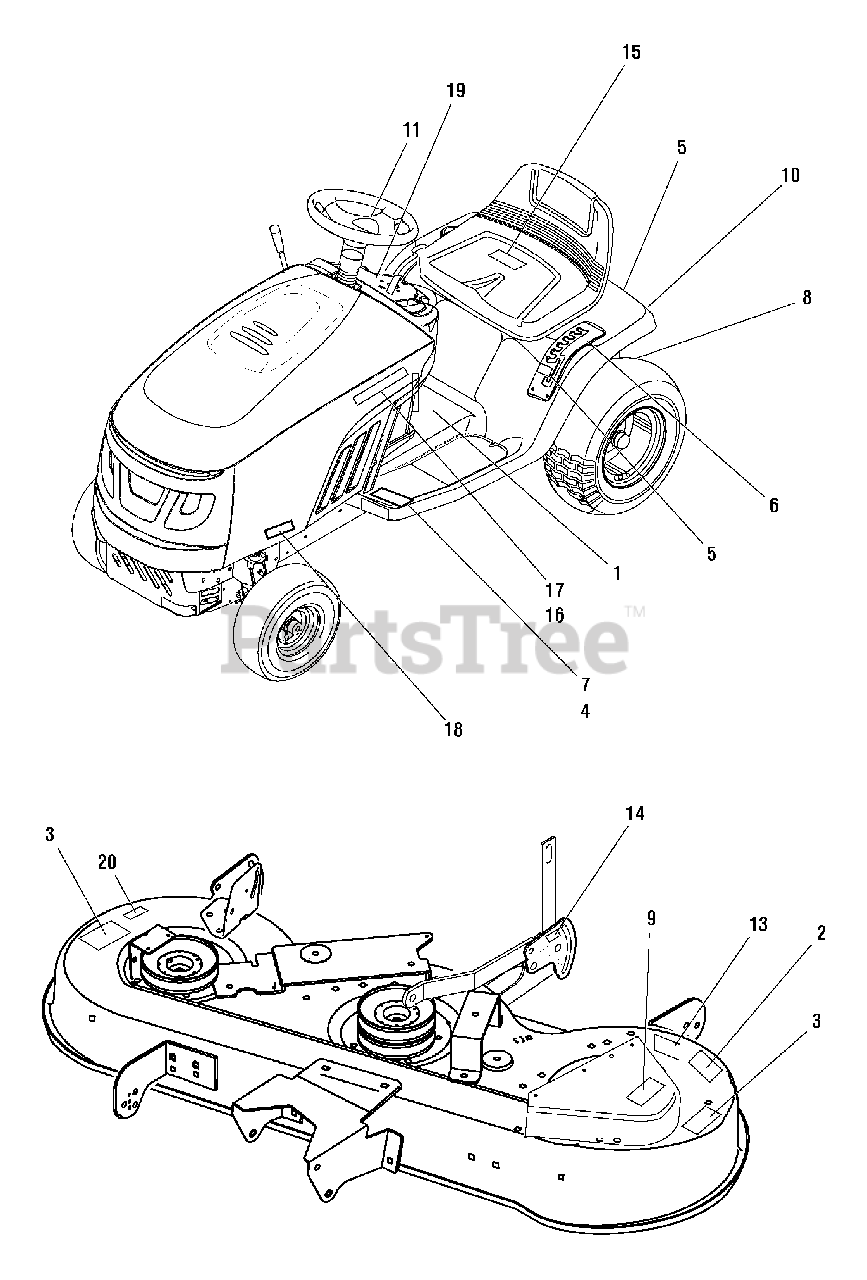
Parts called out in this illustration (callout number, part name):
1	DECAL, Umber
2	DECAL, No Step
3	DECAL, Danger do not Operate w/o Deflector
3	DECAL, Danger, Mower Deck
4	DECAL, Drive Pedal
5	DECAL, Deck Level
6	DECAL, Height of Cut
7	DECAL, Belt, Clutch
8	DECAL, Weight Limitation
9	DECAL, Deck, 46
10	DECAL, Snapper Logo, Rear
11	DECAL, Logo, Steering Wheel
13	DECAL, Gage Wheel Instruction
14	DECAL, Gage Wheel Leveling
15	DECAL, Hydro Release
16	DECAL, Logo, Hood, Right
17	DECAL, Logo, Hood, Left
18	DECAL, LT130/23 HP
19	DECAL, Dash, Electric PTO
20	DECAL, Pinch Point
